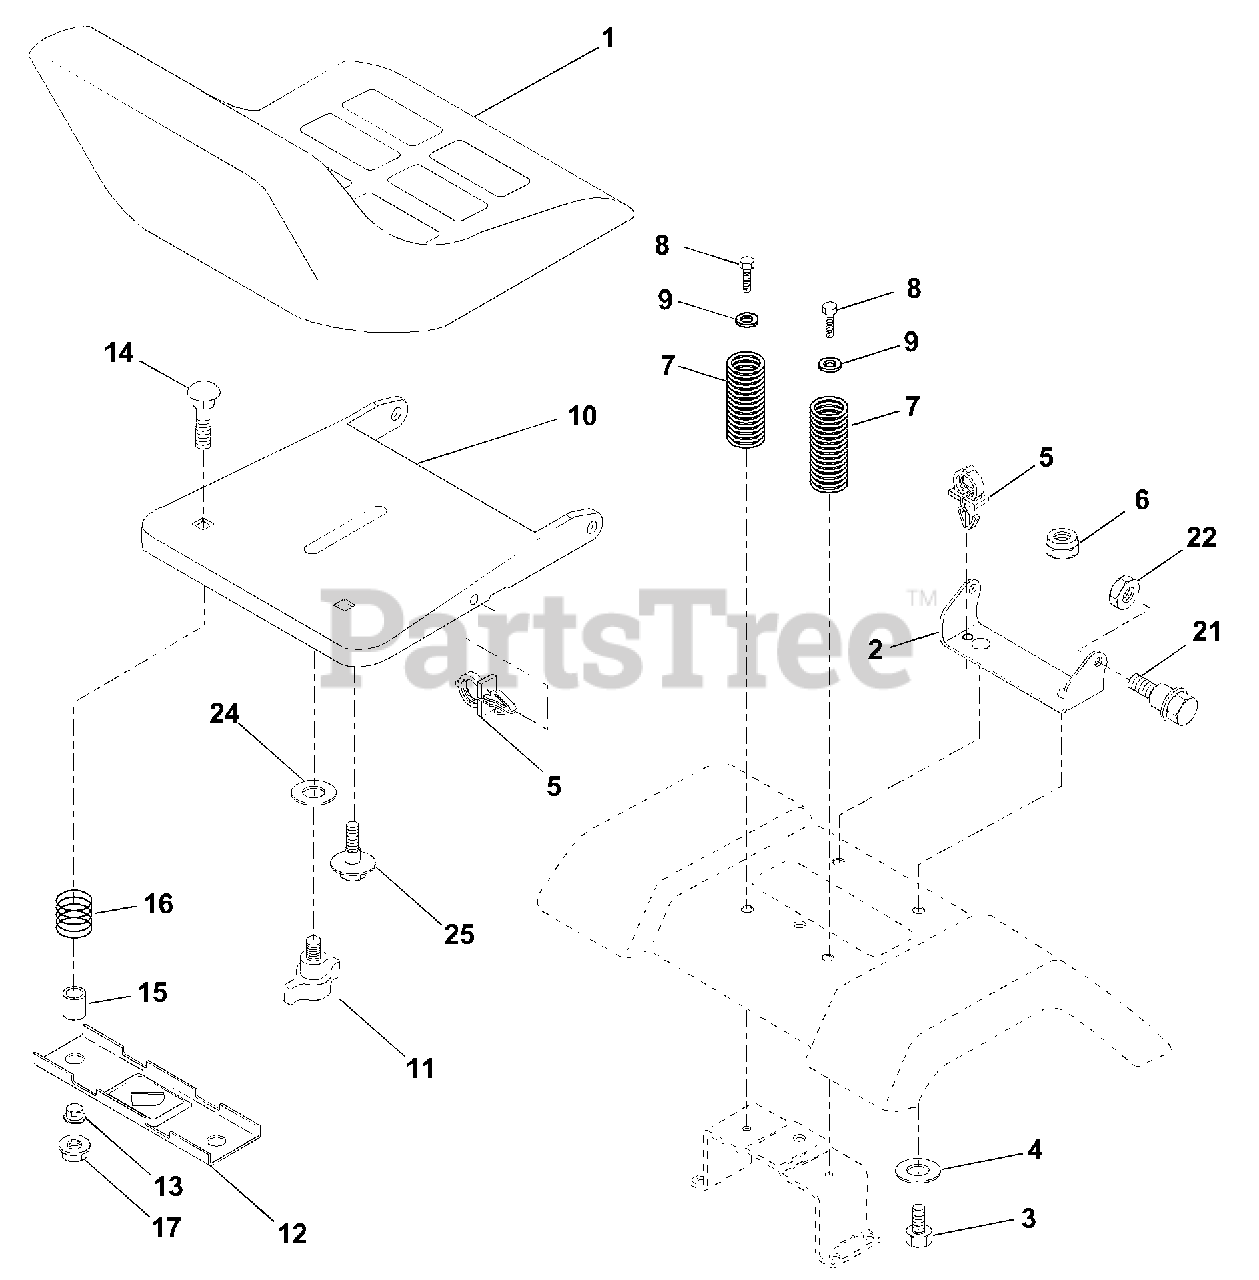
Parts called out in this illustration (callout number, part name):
1	Seat
2	Bracket Pivot Seat 8 720
3	Bolt Fin Hex 3/8-16 Unc X 1
4	Washer 13/32 X 1 X 10 Ga
5	Clip Push-In
6	Nut Hex w/Ins. 3/8-16 Unc
7	Spring Seat Cprsn 2 250 Blk Zi
8	Screw 3/8-16 X 1.5
9	Washer 13/32 X 1 X 14 Ga.
10	Pan Seat
11	Knob Seat
12	Bracket Mounting Switch
13	Bushing Snap Blk Nyl 50 Id
14	Bolt Rdhd Sqnk 1/4-20x1-1/2
15	Spacer Split 28x 88
16	Spring Cprsn
17	Nut Lock 1/4 Lge Flg Gr 5 Zinc
21	Bolt Shoulder 5/16-18 Unc
22	Nut Hex Lock W/Ins 5/16-18
24	Washer 17/32 X 1-3/16 X 12 Ga.
25	Bolt Shoulder 5/16-18 X 62
